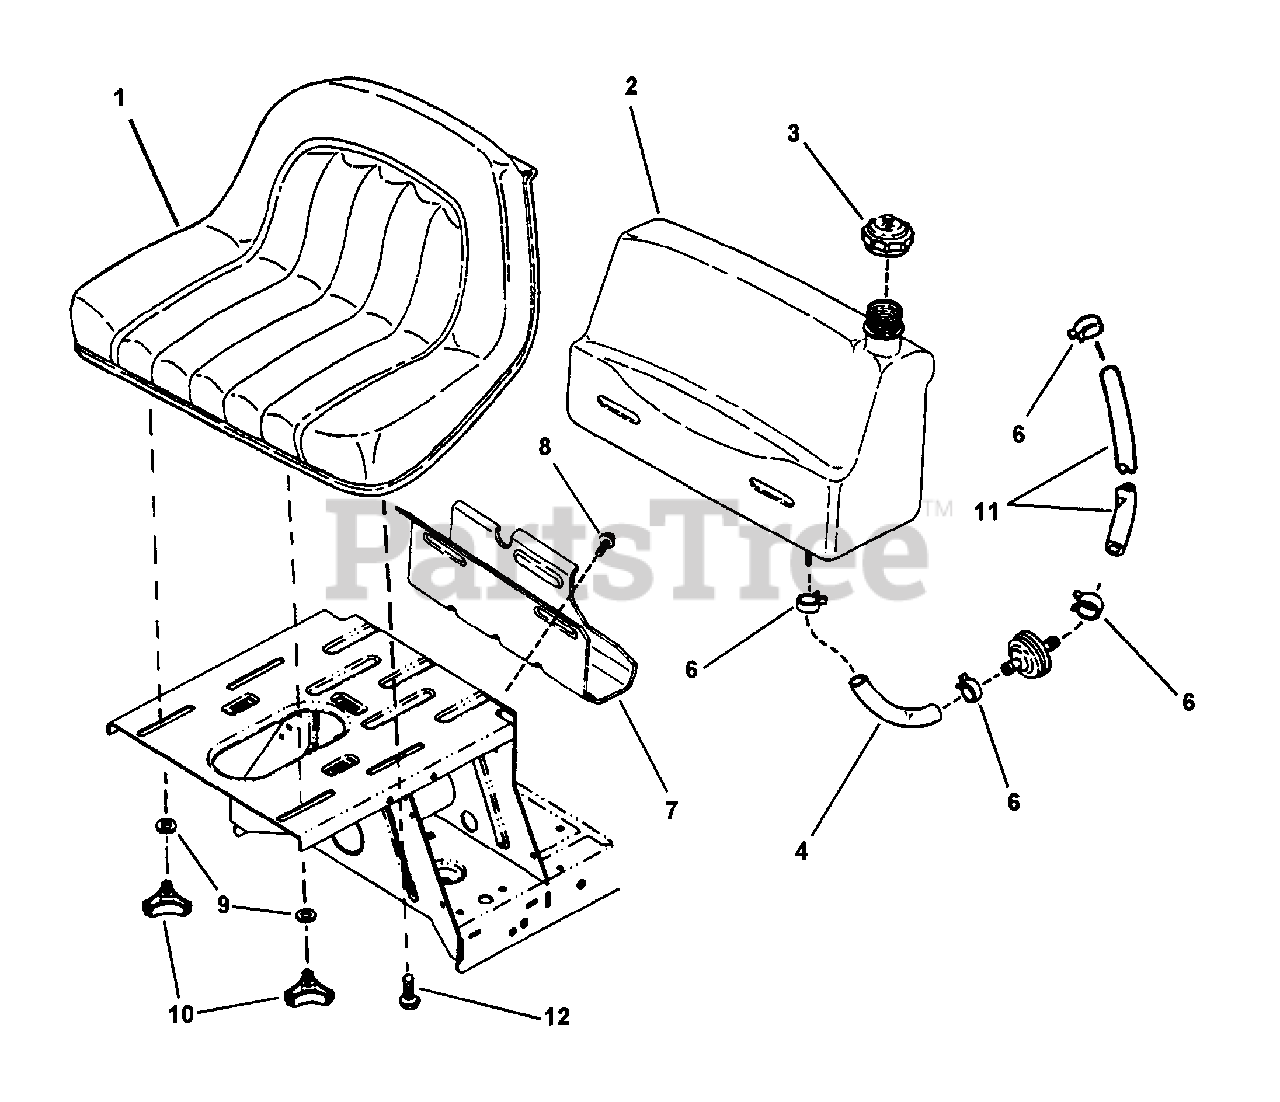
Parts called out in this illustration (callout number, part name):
1	SEAT, Operator (Series 17)
2	ASSEMBLY, Fuel Tank
3	CAP, Fuel Tank
4	HOSE, Fuel (8-1/2" Long)
6	CLAMP, Fuel Line
7	BRACKET, Fuel Tank (Rear)
8	SCREW, 5/16-18 x 1/2" Pan Head Self-Tap
9	SPACER, 21/64"
10	KNOB, 3-Prong Seat
11	HOSE, Fuel (3-1/2" Long)
12	BOLT, 5/16-18 x 1/2" Hex Flange Lock
